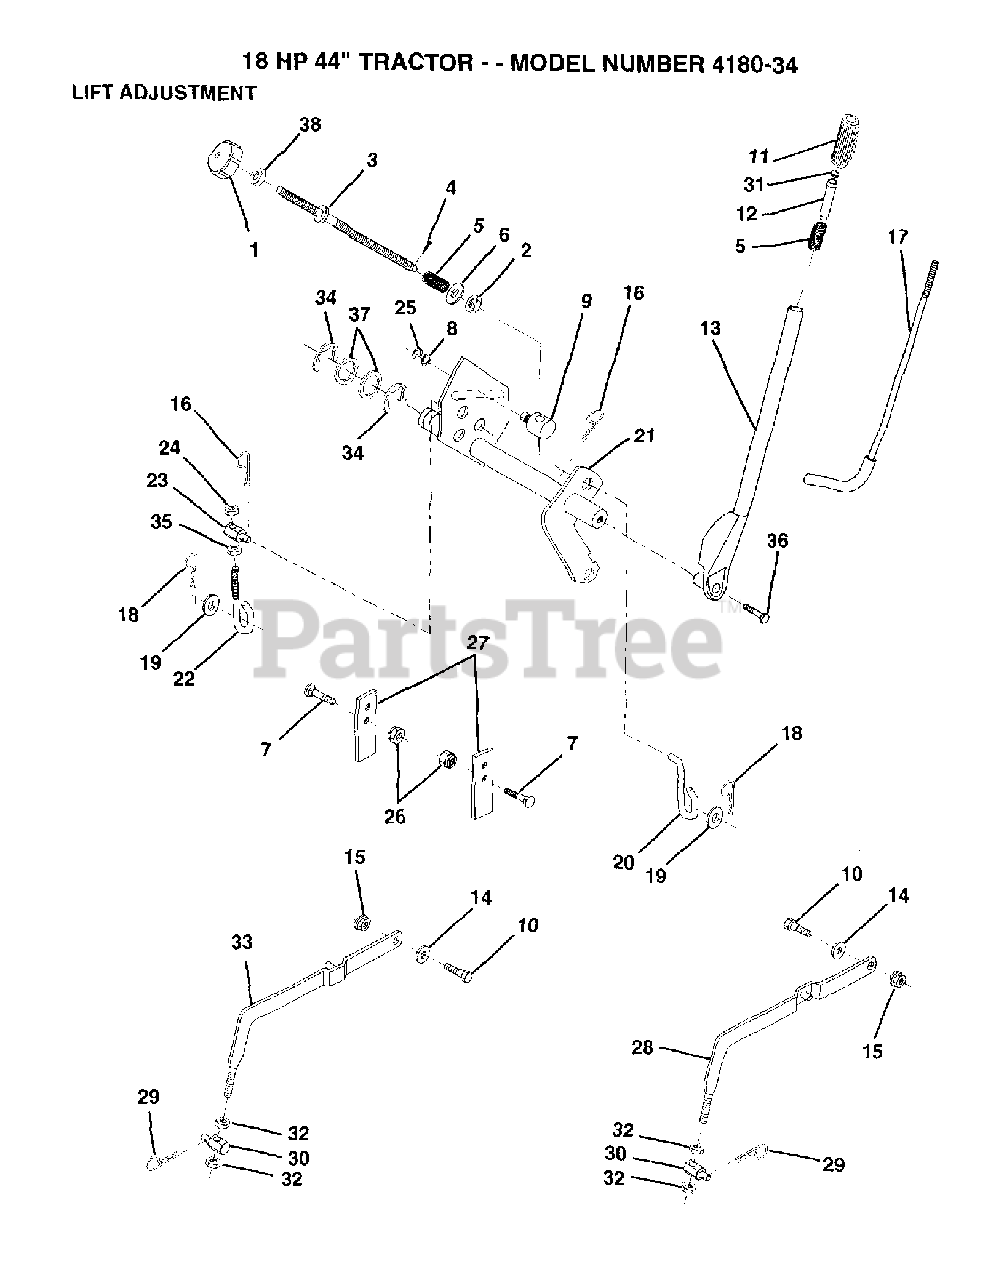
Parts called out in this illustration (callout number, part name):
1	KNOB INF 3/8-16
3	ROD LIFT LT
6	WASHER
8	WASHER
9	TRUNION LT
10	BOLT, SHOULDER LT
11	GRIP
12	PLUNGER BUT KIT
13	LIFT LEVER KIT
14	WASHER T
16	RETAINER SPRING
17	LEVER ROD LT
18	SPRING.RETAINER
19	WASHER T
20	LIFT LINK LT
21	Lift Shaft Assembly
22	LINK ADJ T
23	TRUNNION T
24	NUT LOCK YTH
25	LOCKNUT
28	RH SUSP ARM ASM
29	SPRING H
31	PLUNGER BUT KIT
33	LH SUSP ARM ASM
36	Hex Bolt
37	Poulan TBD
38	NUT
